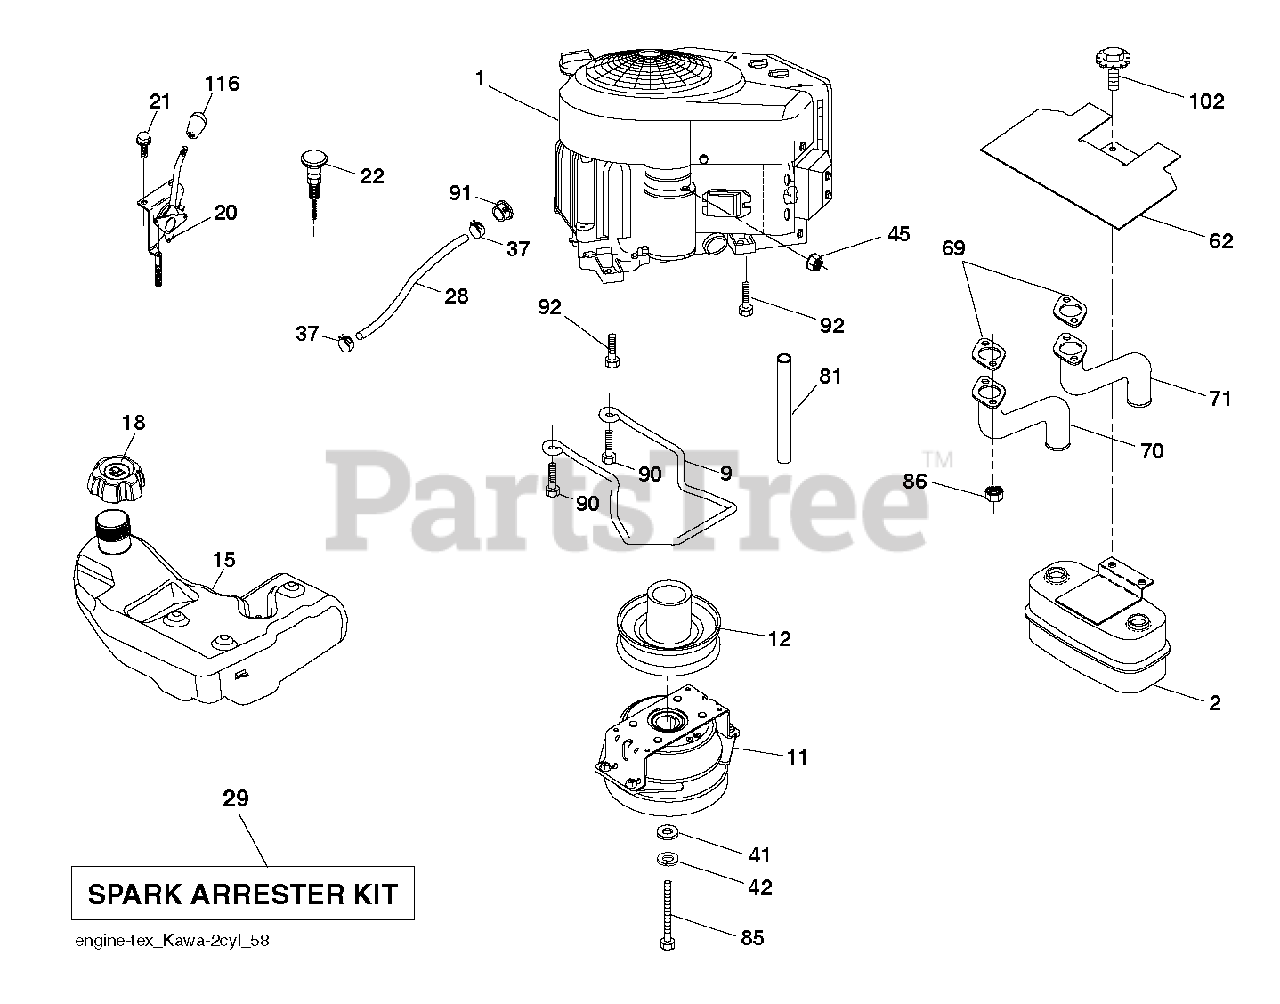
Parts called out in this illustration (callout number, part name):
2	MUFFLER.ASM.TWN.EXTNDED.DFLCTR
9	KEEPER.BELT.ENG.4.25"2.BLT.431
11	CLUTCH.OGURA.5.0PD.GT1.5A-EH07
12	PULLEY.ENGINE.TUFFTORQ
15	Tank Assembly, 3Gal EPA
18	CAP ASSY FUEL 3" BLACK
20	CONTROL.THROTTLE.PRO.
21	SCREW.#10 X 0.750.BOS
22	CONTROL, CHOKE
28	LINE.FUEL.64"REAR.EMIS
29	KIT.SPARK ARRESTOR 794945 B&S
37	HOSE CLAMP
42	LOCKWASHER
45	NUT
62	SHIELD.HEAT.MUFFLER
70	TUBE.EXHAUST.LH.FR961/FR730
71	TUBE.EXHAUST.RH.FR961/FR730
81	TUBE, DRAIN OIL ASM.
85	BOLT.HEX.7/16-20X3.75.GR5.RED
86	NUT.HEX.FLANGE.TOPLOCK
90	SCREW 3/8-16X1
91	BUSHING.1.375OD
92	SCREW 3/8-16X1
102	SCREW
116	KNOB - SHIFT
